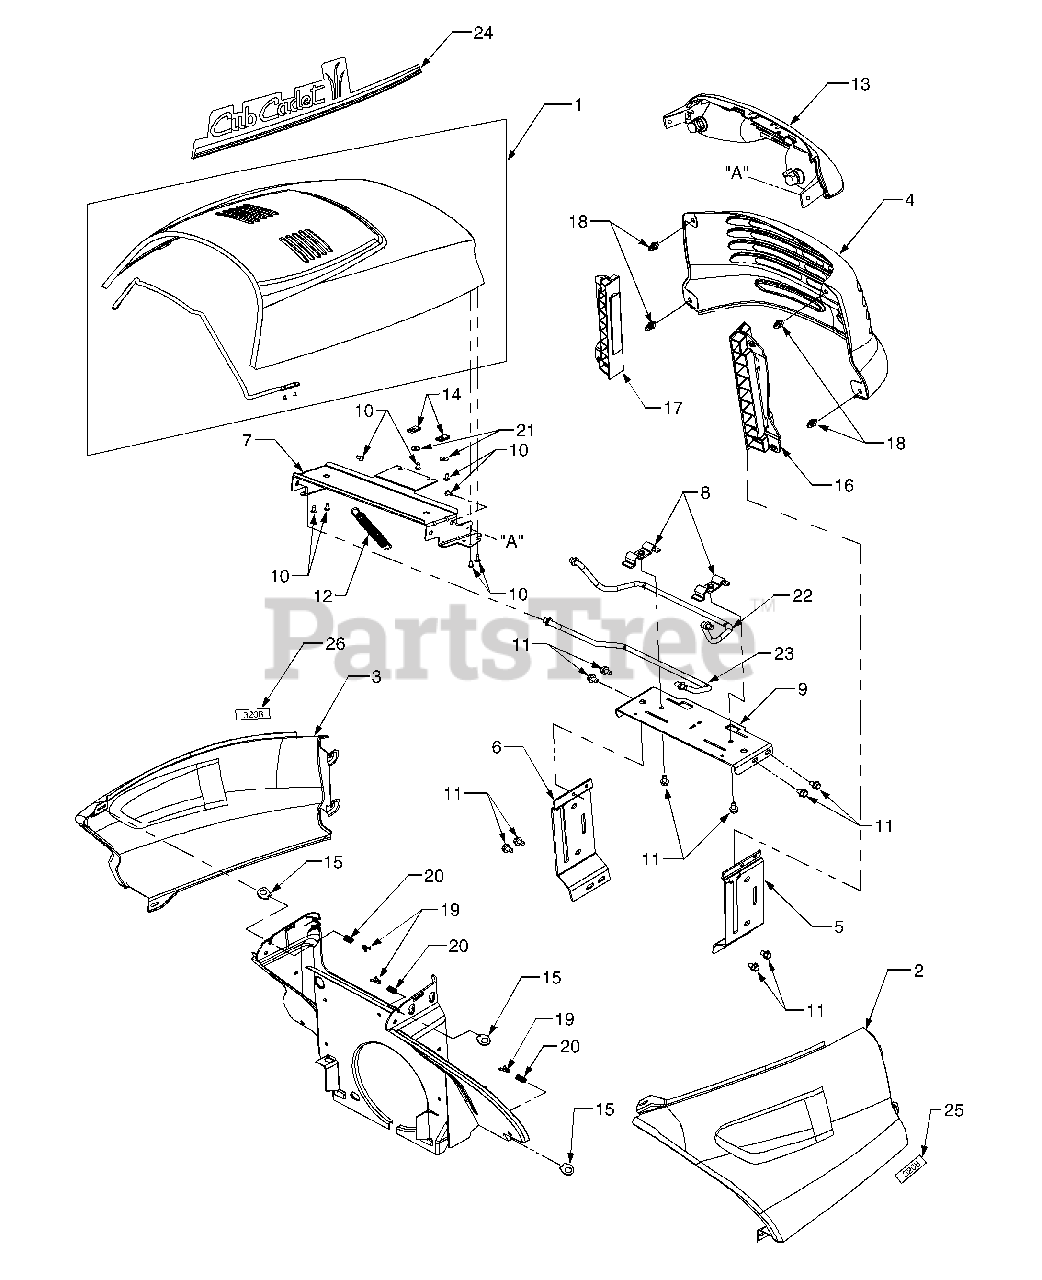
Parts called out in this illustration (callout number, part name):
1	Hood w/Support Rod Assembly
2	Side Panel, RH
3	Side Panel, LH
4	Grille, Series 3000
5	Support, Grille - RH
6	Support, Grille LH
7	Bracket, Upper Hood
8	Bracket, Rod Retainer
9	Support, Hood
10	Screw, Truss Hd, Tapp, #10-16 x .5
11	Screw, Hex Wash. Hd. Tapp 5/16-18 x .5
12	Spring, Extension
13	Headlight Assembly (Lens glued to reflector)
14	Nut, U-type Speed, #10
15	Latch, 1/4 Turn
16	Mount, Side Panel/Grille RH
17	Mount, Side Panel/Grille LH
18	Fastener, Grille Mount
19	Clip, Spring
20	Spring, Compression
21	Washer, Flat, .194 x .62 x .063
22	Rod, Upper Hood
23	Rod, Lower Hood
24	Graphic, Hood - RH
25	Graphic, 3208
